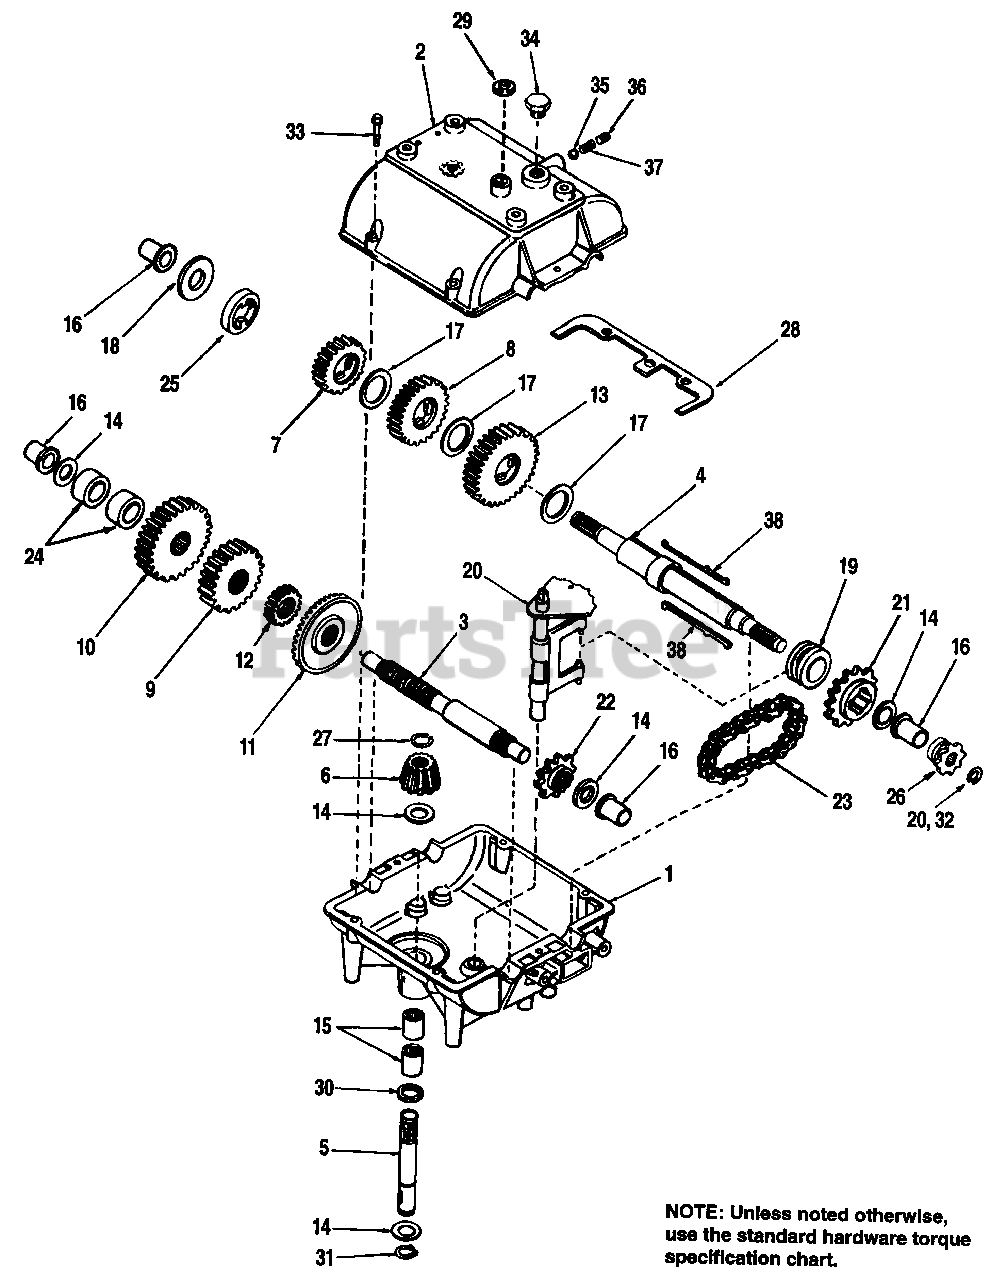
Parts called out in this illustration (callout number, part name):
1	CASE, Transmission
2	COVER, Transmission
3	SHAFT, Counter
4	SHAFT, Output & Brake
5	SHAFT, Input
6	BEVEL PINION, Input
7	GEAR, Spur (20 teeth)
8	GEAR, Spur (30 teeth)
9	GEAR, Spur (20 teeth)
10	GEAR, Spur (30 teeth)
11	GEAR, Bevel (42 teeth)
12	GEAR, Spur (12 teeth)
13	GEAR, Spur (37 teeth)
14	WASHER, Thrust
15	BEARING, Needle
16	BUSHING, Flanged
17	WASHER, Thrust
18	WASHER, Thrust
19	COLLAR, Shift
20	ROD & FORK ASSY., Shift
21	SPROCKET (14 teeth)
22	SPROCKET (10 teeth)
23	CHAIN, Roller (No. 41 chain, 22 links)
24	SPACER (1-1/8" O.D. x 3/4" I.D. x 3/8" thick)
25	SPACER (1-3/8" O.D. x 1/8" I.D. x 3/8" thick)
26	SPROCKET, (8 teeth)
27	RING, Retaining
29	SEAL, Square Cut
31	RING, Retaining
32	RING, Retaining
33	SCREW, Fl. Hex Hd., Thread Forming, 1/4-20 x 1-1/4
34	PLUG, Threaded
35	BALL, Steel, 5/16"
36	SCREW, Set, 3/8-16 x 3/8
